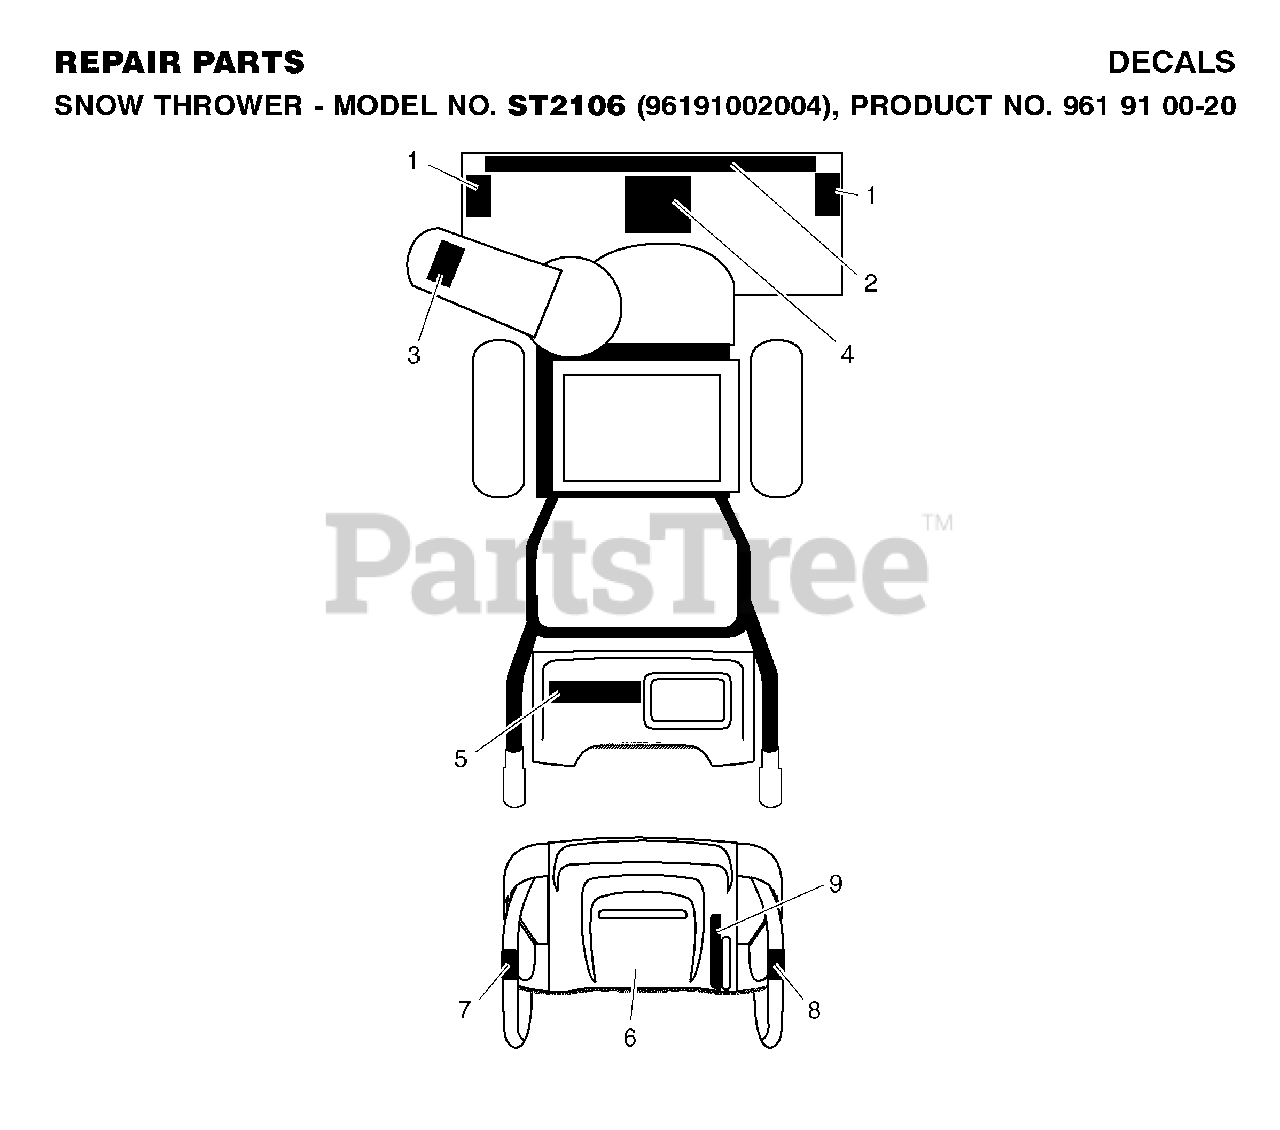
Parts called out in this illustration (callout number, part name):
1	DECAL.AUGER.SAFETY.
3	DECAL.CHUTE.SAFETY.
4	DECAL.AUGER."
6	DECAL.CONSOLE.INSTRUCTION
